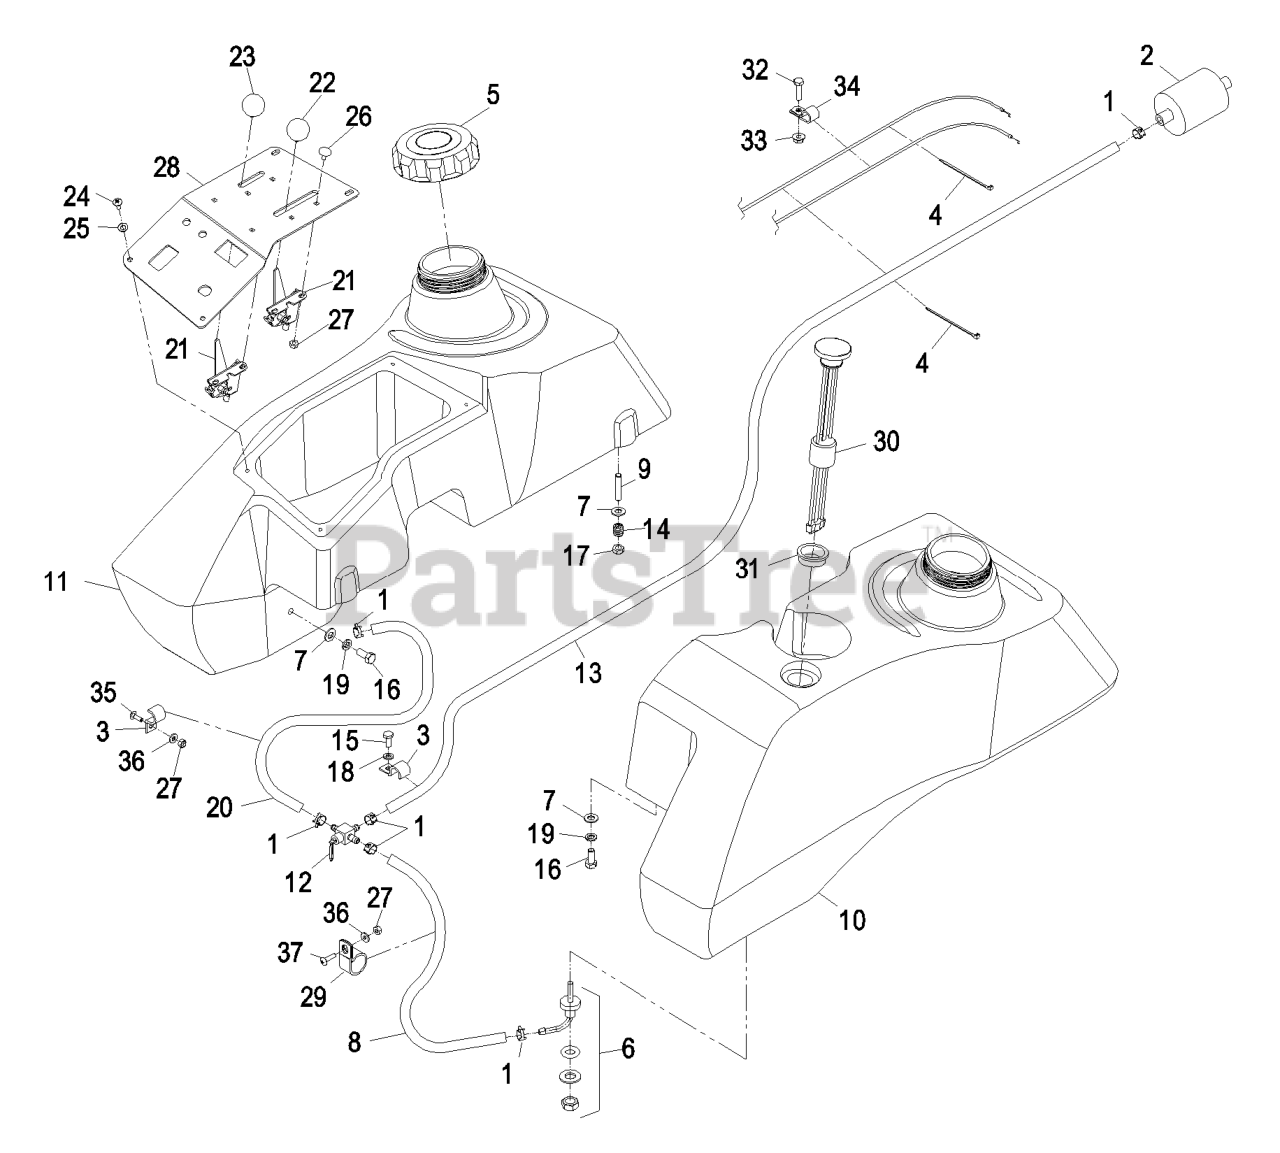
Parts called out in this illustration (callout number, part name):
2	Kohler Part No. 2405002 Fuel Filter
3	CLIP-HALF, LOOM
4	TIE-PLASTIC
6	FITTING-FUEL, BULKHEAD
7	WASHER-PLAIN
8	HOSE-FUEL
9	STUD
10	ASM,FUEL TANK LH
12	VALVE-FUEL
13	HOSE,FUEL
14	SPRING-TANK, FUEL
15	SCREW-HH
16	SCREW-HH
17	NUT-LOCK, NI
18	WASHER-LOCK
19	WASHER-LOCK
21	CABLE-THROTTLE
22	KNOB-BALL
23	KNOB-BALL, BLACK
24	SCREW-PTH
25	WASHER-SPRING
26	BOLT-CARR
27	NUT-LOCK, NI
29	CLIP-LOOM
31	CONTACT ORDER SERVICES
32	SCREW-HH
34	CLIP-LOOM
35	BOLT-CARR
36	WASHER-FLAT
37	SCREW-HEAD, TRUSS
